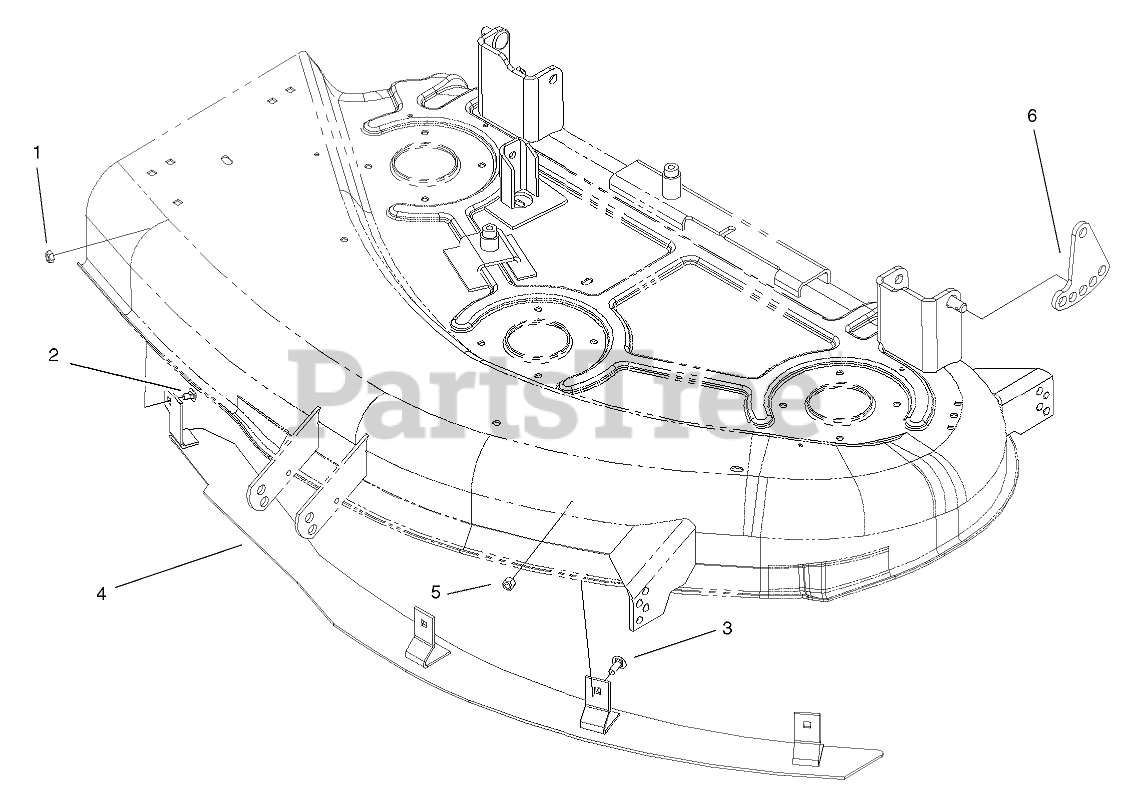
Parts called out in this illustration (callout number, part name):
1	NUT-LOCK, NI
2	SCREW-CARR
3	SCREW-CARR
5	NUT-LOCK, NI
6	LINK-HOC, ADJUSTING
